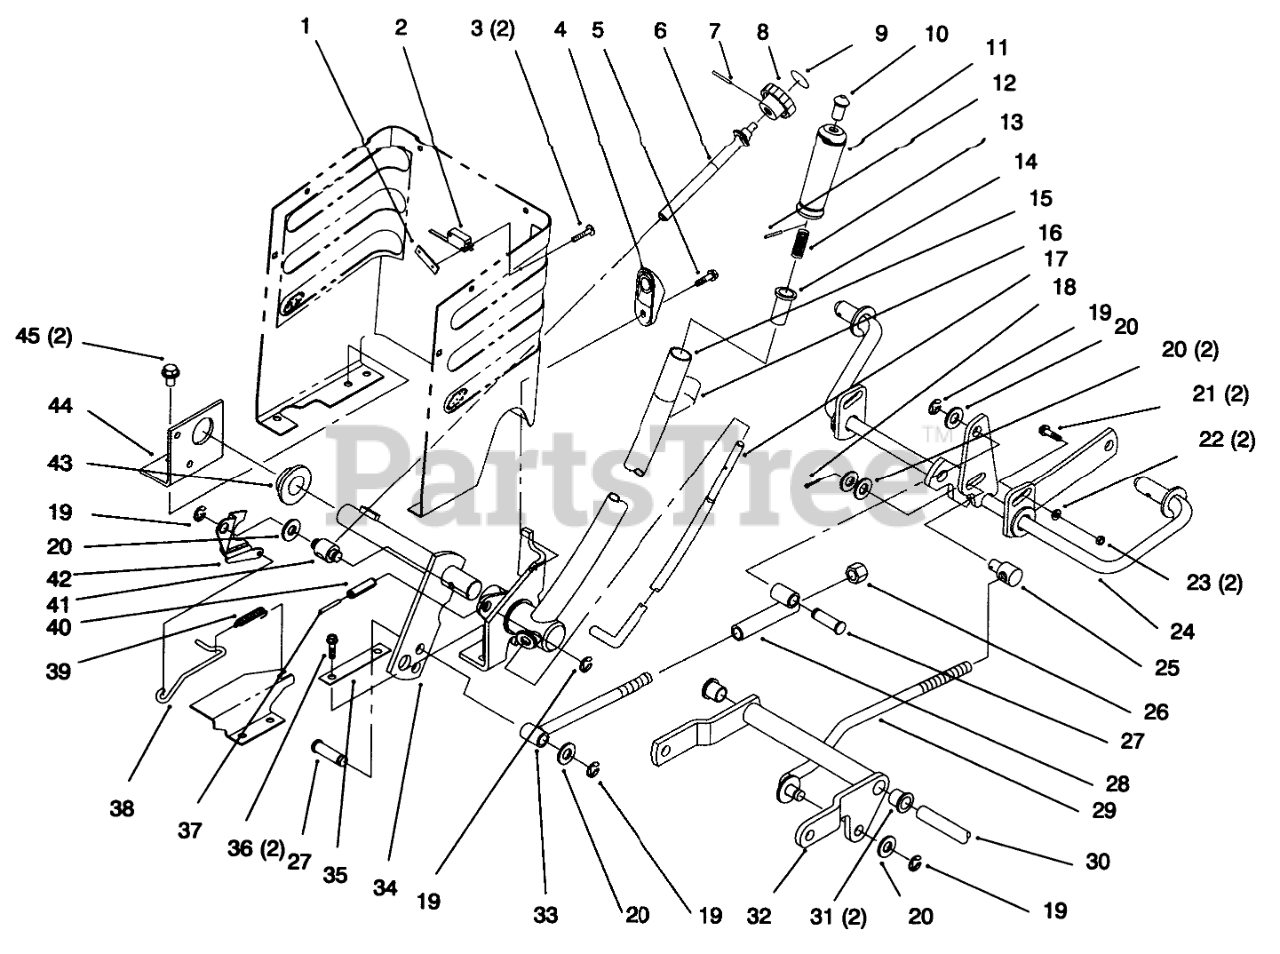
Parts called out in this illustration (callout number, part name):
1	NUT-SPEED
2	SWITCH-MICRO
3	SCREW-HH
4	WEDGE - HOC
5	SCREW-HWH
6	ROD - HOC
7	PIN-SPIROL
9	DECAL-HEIGHT KNOB
10	TIP-ROD
11	GRIP-HANDLE
12	PIN-SPIROL
13	SPRING-COMPRESSION
14	RETAINER-SPRING
15	LEVER-LIFT
16	Decal Lift (Only On: 72046)
16	Decal-Lift (Only On: 72064)
17	ROD-LEVER, LIFT
18	PIN-COTTER
19	RING-RETAINING, EXTERNAL
20	WASHER-FLAT
21	BOLT-CARR
22	WASHER-FLAT
23	NUT-LOCK, NI
24	SHAFT-GAGE
25	ROD-TRUNNION LIFT
26	NUT-LOCK, NI
30	SHAFT-PIVOT, PEDAL
31	BUSHING-FLANGE
32	ARM-PIVOT
34	SHAFT-LIFT
36	SCREW-HWHTF
37	PIN-SPRING
38	ROD - HOC INDICATOR
39	SPRING - EXTENSION
40	PIN-ROLL
41	TRUNNION
42	PLATE - HOC GAGE
43	BEARING-FLANGE
44	BRACKET-PIVOT, LINKAGE
45	SCREW-HWHTF
